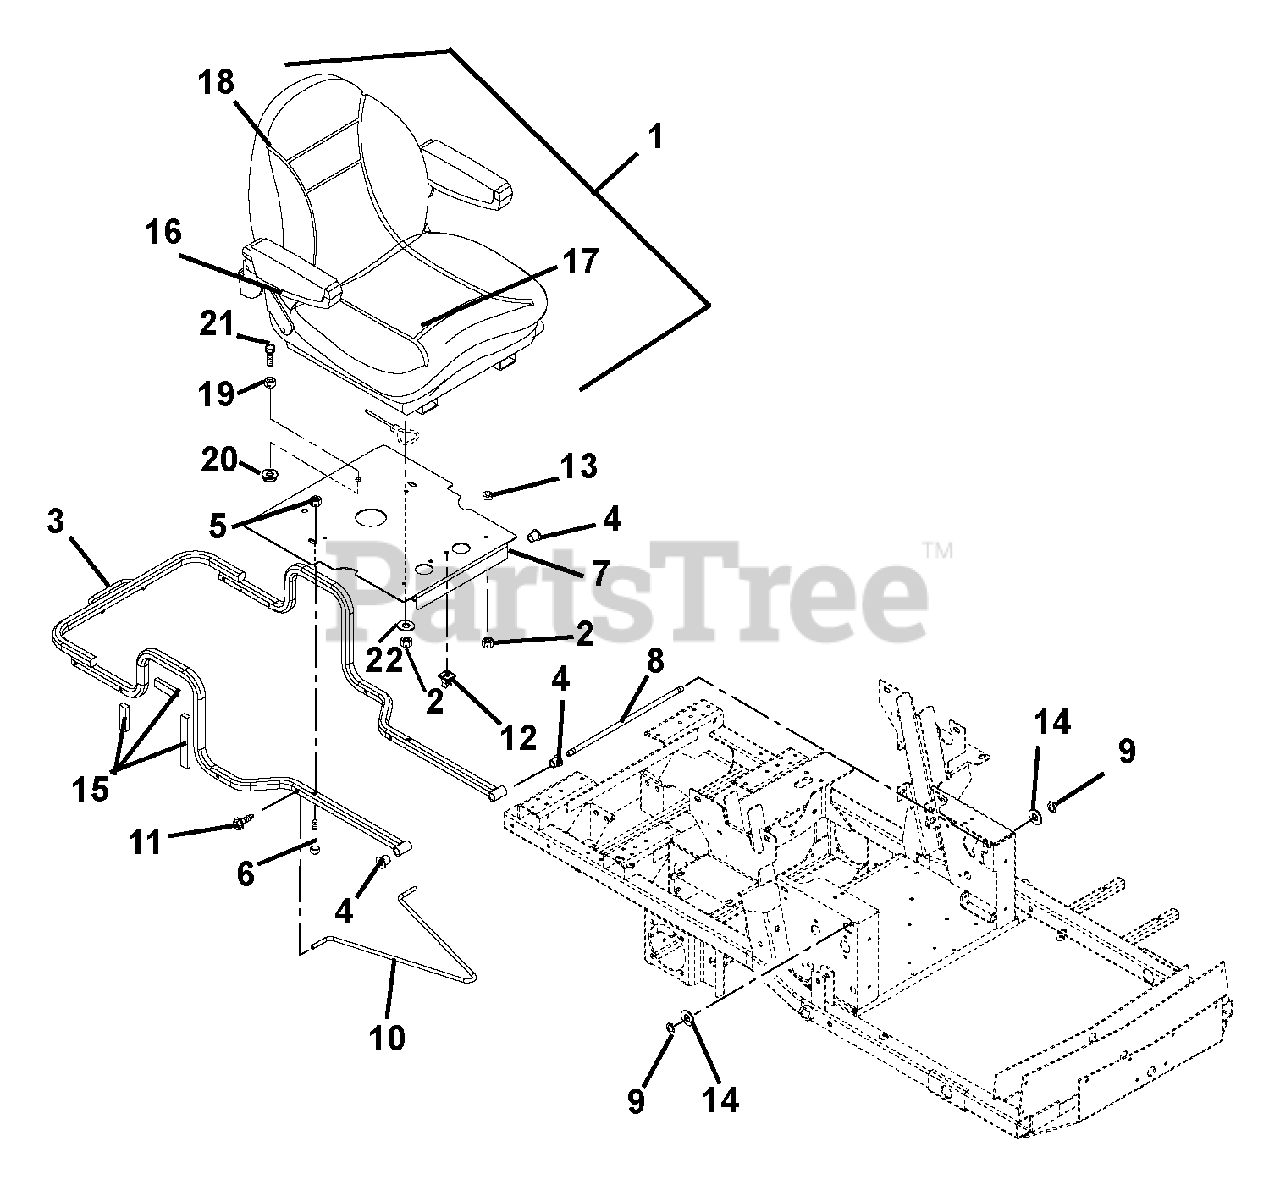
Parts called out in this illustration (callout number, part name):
1	Seat, Suspension
2	Nut, Locking Top Flange .31-18
3	Weldment, Hood Frame
4	Bushing, Flange .515 x .750 x .745 x 1.00
5	Nut, Locking Top Flange .38-16
6	Bolt, Rib Neck .38-16 x 1.50
7	Weldment, Seat Pivot Mount
8	Rod, Seat Frame Pivot
9	Ring, Retaining External .500 x .050
10	Rod, Prop
11	Screw, Tapping .25-20 x .50 Hex Washer Head
13	Bushing, Sleeve .377 x .624 x .235
14	Washer, Flat Steel .531 x 1.06 x .095
15	Tape, VHB
16	Kit, Arm Pad
17	Kit, Seat Cushion
18	Kit, Back Cushion
19	Nut, Hex .50-13
20	Nut, Locking Top Flange .50-13
21	Bolt, Hex .50-13 x 1.50
22	Washer, Flat Steel .328 x 1.00 x .094
